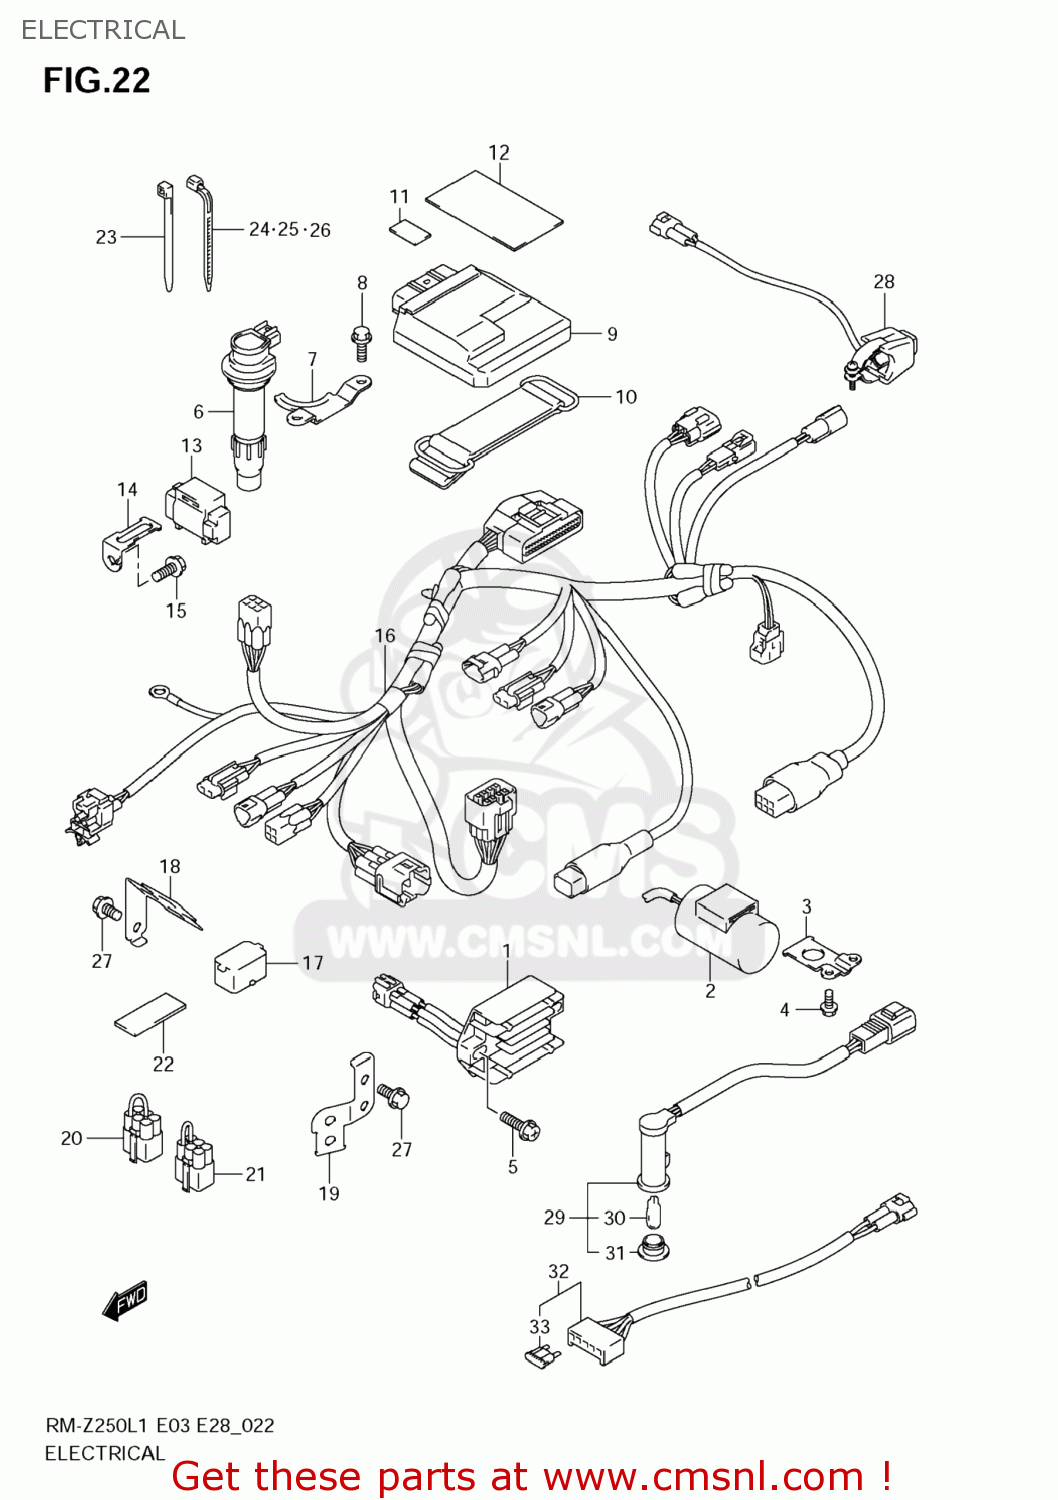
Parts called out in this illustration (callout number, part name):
1	RECTIFIER ASSY
2	CONDENSER ASSY
3	BRACKET,CONDENSER
4	BOLT(6X10)
5	SCREW
6	COIL ASSY,IGNITION
7	RETAINER,IGNITION COIL
8	BOLT
9	CONTROL UNIT,FI
10	BAND,CDI UNIT(L:80)
11	CUSHION(30X50X3)
12	CUSHION(30X50X3)
13	SENSOR ASSY,FUEL CUT
14	BRACKET,FUEL CUT SENSOR
15	SCREW
16	HARNESS,WIRING
17	CAP,TS
18	BRACKET,COUPLER
19	BRACKET,COUPLER
20	WIRE,SHORT
21	WIRE,SHORT
22	PROTECTOR,WIRING HARNESS
23	CLAMP(L:95)
24	CLAMP(L:95)
25	CLAMP(L:125)
26	CLAMP(L:165)
27	BOLT
28	SWITCH ASSY,ENGINE STOP
29	LAMP ASSY,FI INDICATOR
30	BULB(12V3.4W,T10)
31	LENS(RED)
32	WIRE,BATTERY
33	FUSE(10A)
